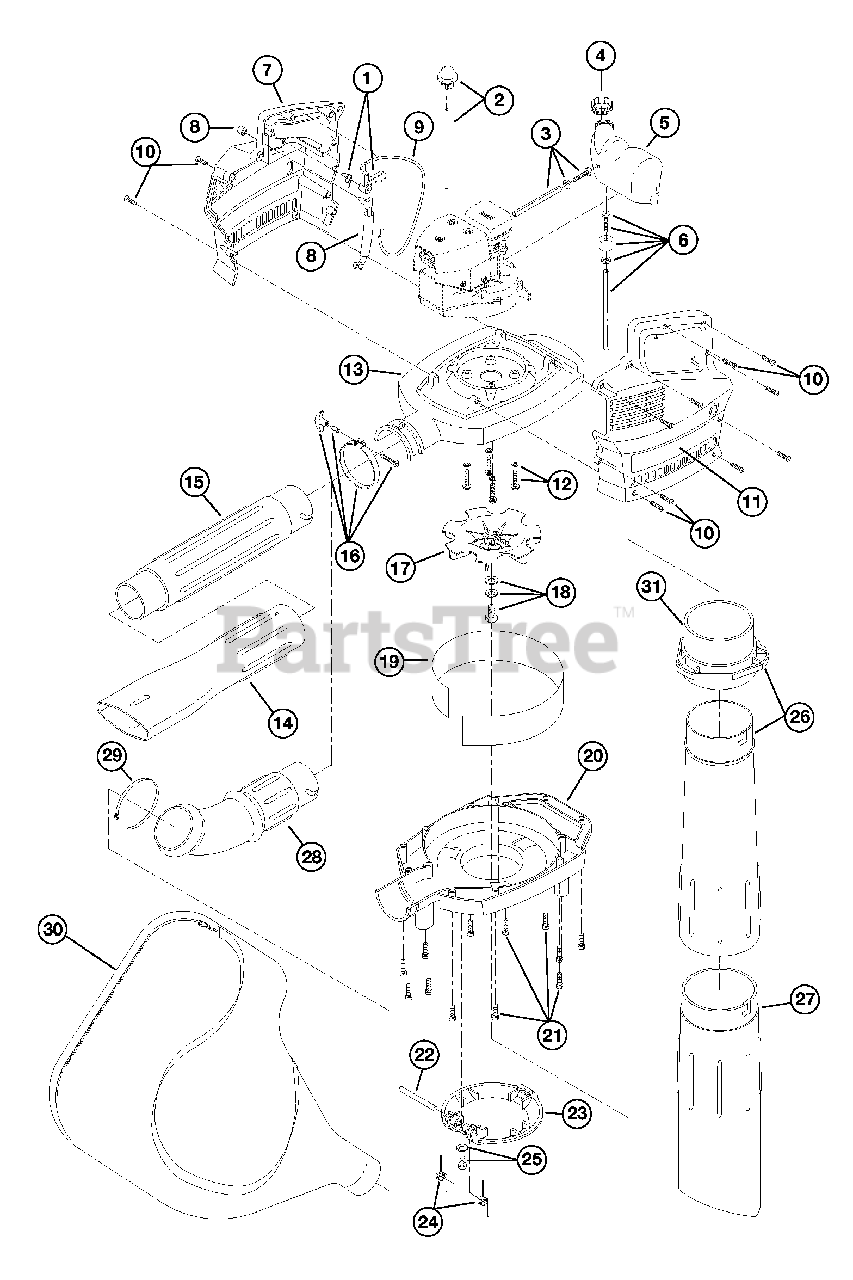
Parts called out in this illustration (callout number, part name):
1	Trigger Assembly
2	Primer Bulb and Hose Assembly
3	Return Line Assembly
4	Fuel Cap Assembly
5	Complete Fuel Tank Assembly
6	Fuel Line Assembly
7	R.H. Engine Cover
8	Switch and Lead Assembly
9	Throttle Wire and Housing Assembly
10	Mounting Screw Assembly
11	L.H. Engine Cover
12	Mounting Screw Assembly
13	Upper Blower Housing
14	Blower Tube/w Nozzle
15	Blower Tube
16	Clamp Assembly
17	Impeller
18	Mounting Bolt Assembly
19	Impact Shield
20	Lower Blower Housing
21	Mounting Bolt Assembly
22	Hinge Shaft
23	Intake Cover
24	Spring Set
25	Mounting Screw Assembly
26	Upper Vacuum Tube and Adapter
27	Lower Vacuum Tube
28	Elbow
29	Clamp
30	Vacuum Bag Assembly
31	Adapter-Upper Vacuum Tube
